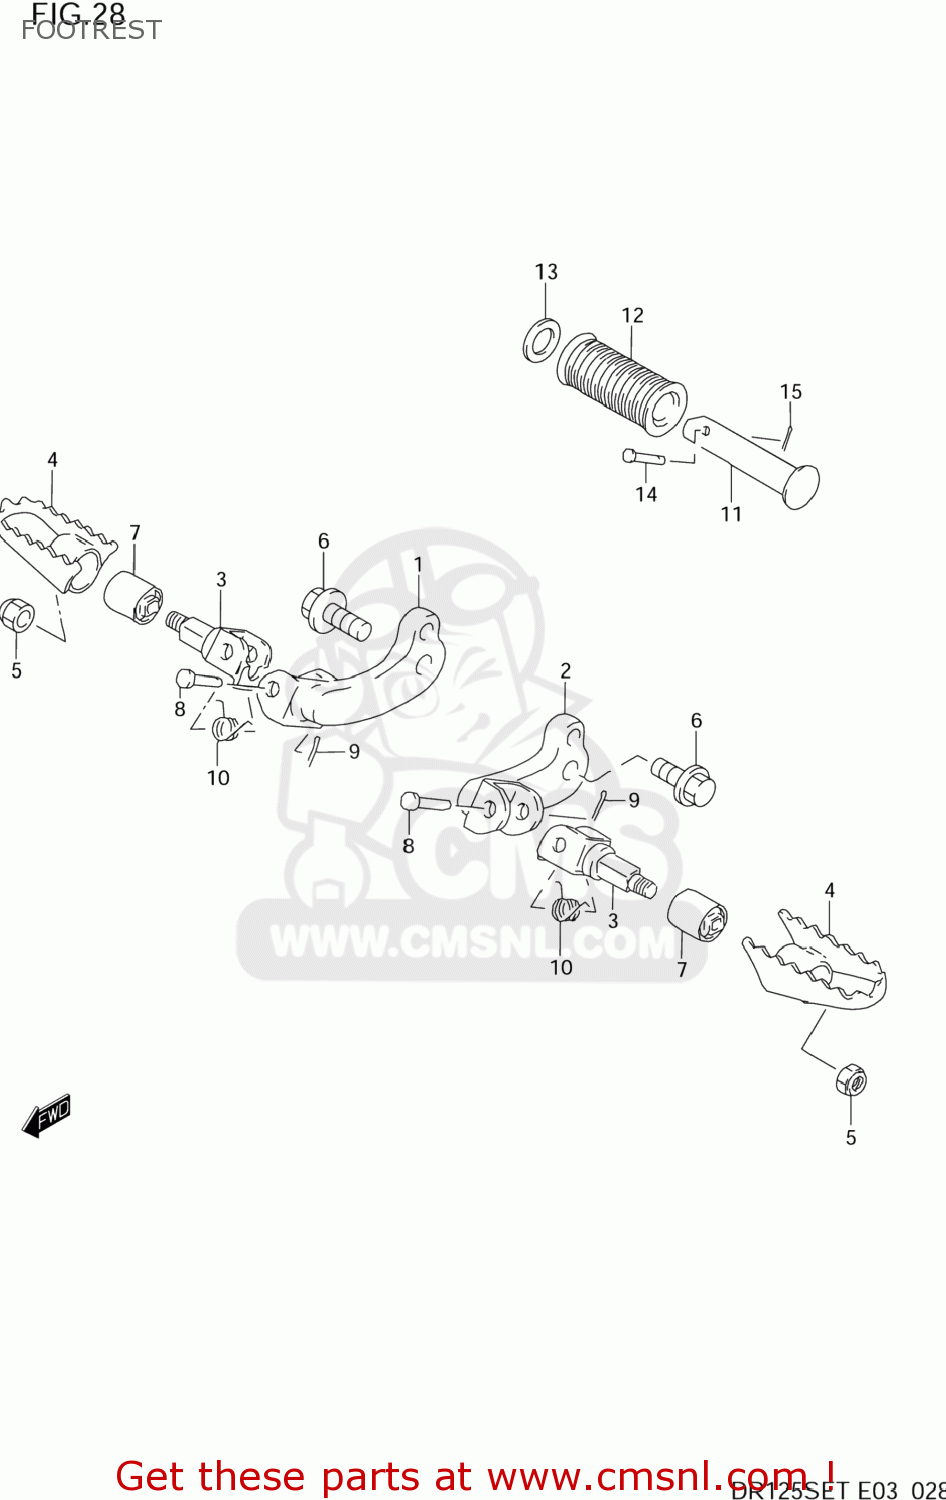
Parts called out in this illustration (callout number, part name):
1	BAR,FR FOOTREST,R
2	BAR,FR FOOTREST,L
3	BRACKET,FR FOOTREST
4	FOOTREST,FR
5	BOLT(12X25)
6	BUSH
7	NUT
8	PIN
9	PIN
10	SPRING
11	BAR,FOOTREST RUBBER
12	RUBBER,PILLION FOOTREST
13	WASHER (19.5X32X2)
14	PIN
15	PIN
